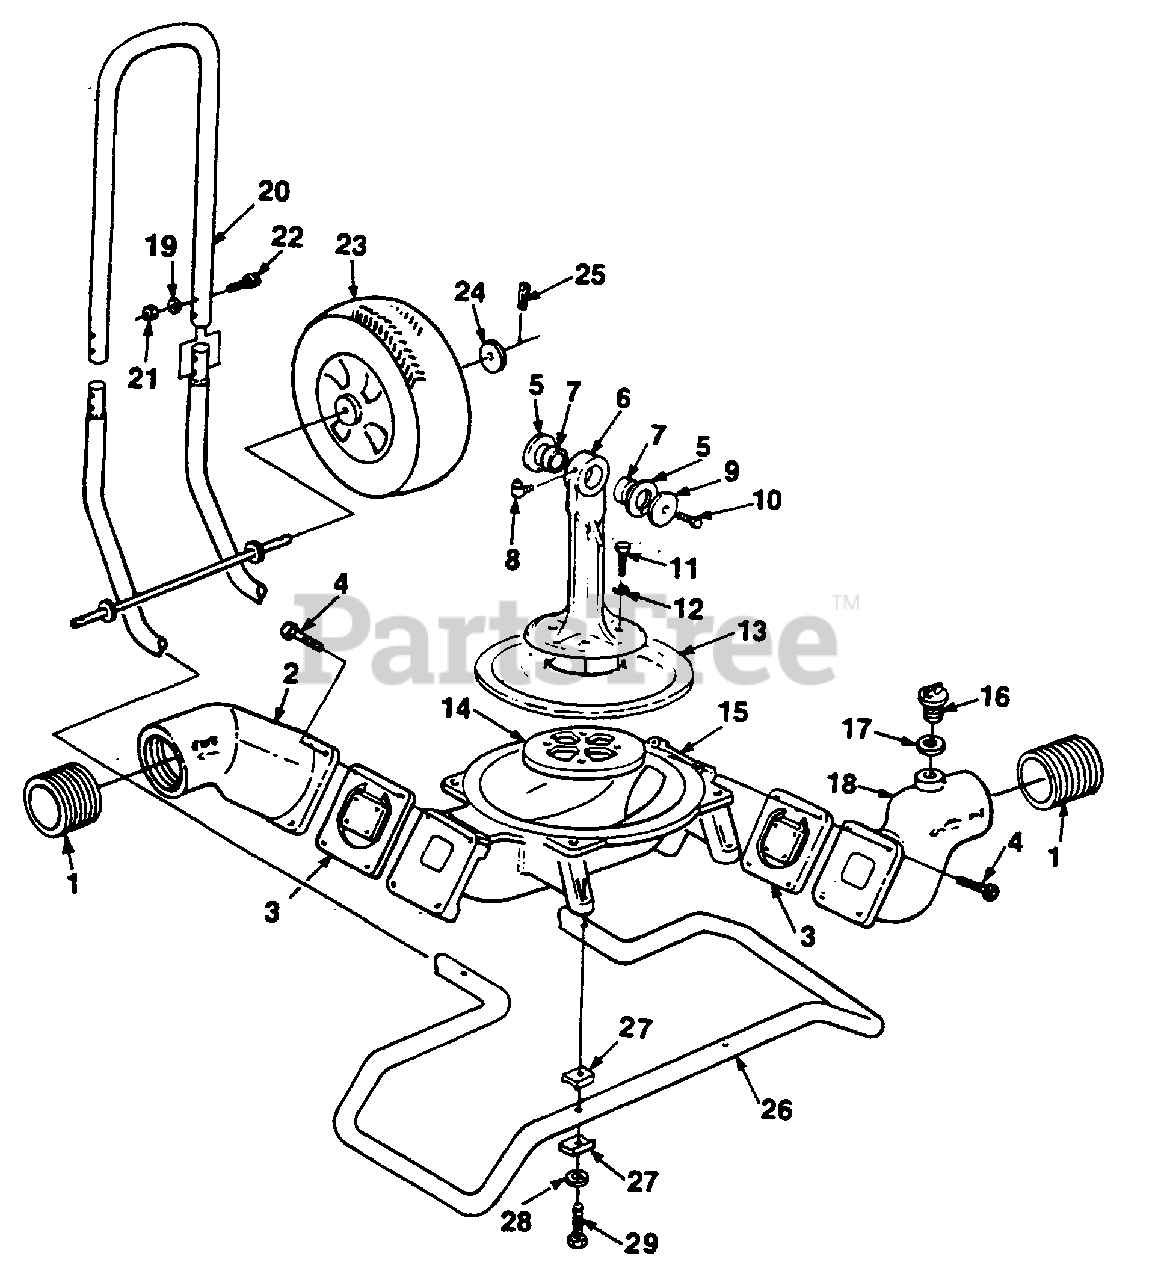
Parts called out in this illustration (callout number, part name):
1	FITTING - Pipe
2	FITTING - Discharge
3	VALVE AND INSERT
4	SCREW - Hex hd. (5/16-18 x 1")
5	WASHER - Thrust, large
6	ROD - Pump
7	BEARING - Needle
8	FITTING - Grease
10	SCREW - Hex hd. (3/8-16 x 3/4")
11	SCREW - Hex hd. (3/8-16 x 1 1/8")
12	WASHER - Lock (3/8")
13	DIAPHRAGM
14	CAP - Diaphragm
15	BODY - Pump (lower)
16	PLUG - Filler
18	FITTING - Suction
19	WASHER - Lock (1/4")
20	HANDLE - Pump
21	NUT (1/4-20")
22	SCREW - Hex hd. (1/4-20 x 1 1/2")
24	WASHER - Flat
25	PIN - Cotter (3/32 x 1 1/8")
26	PUMP SUPPORT 2"
27	SADDLE - 1" Pipe
28	WASHER - Lock (5/16")
29	SCREW - Hex hd. (5/16-1 8 x 2")
